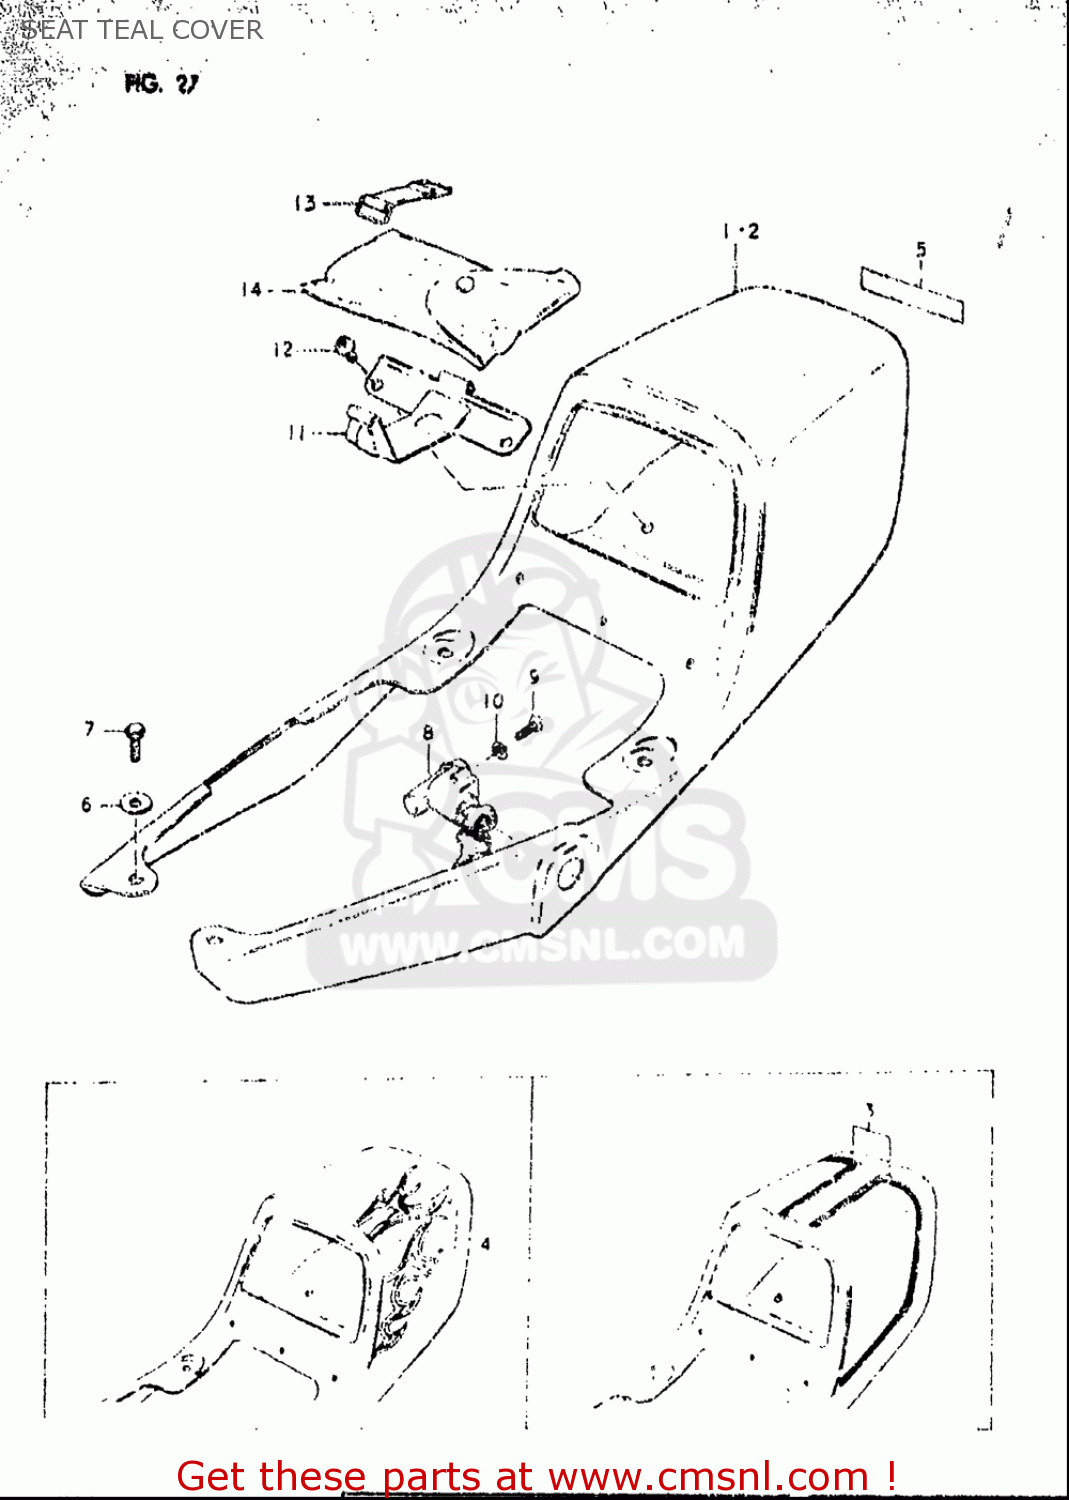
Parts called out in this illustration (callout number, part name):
6	WASHER(6.5X18X1.6)
7	BOLT
8	LOCK ASSY,SEAT
9	SCREW
10	WASHER,LOCK
12	SCREW
13	BAND
14	TOOL ASSY
